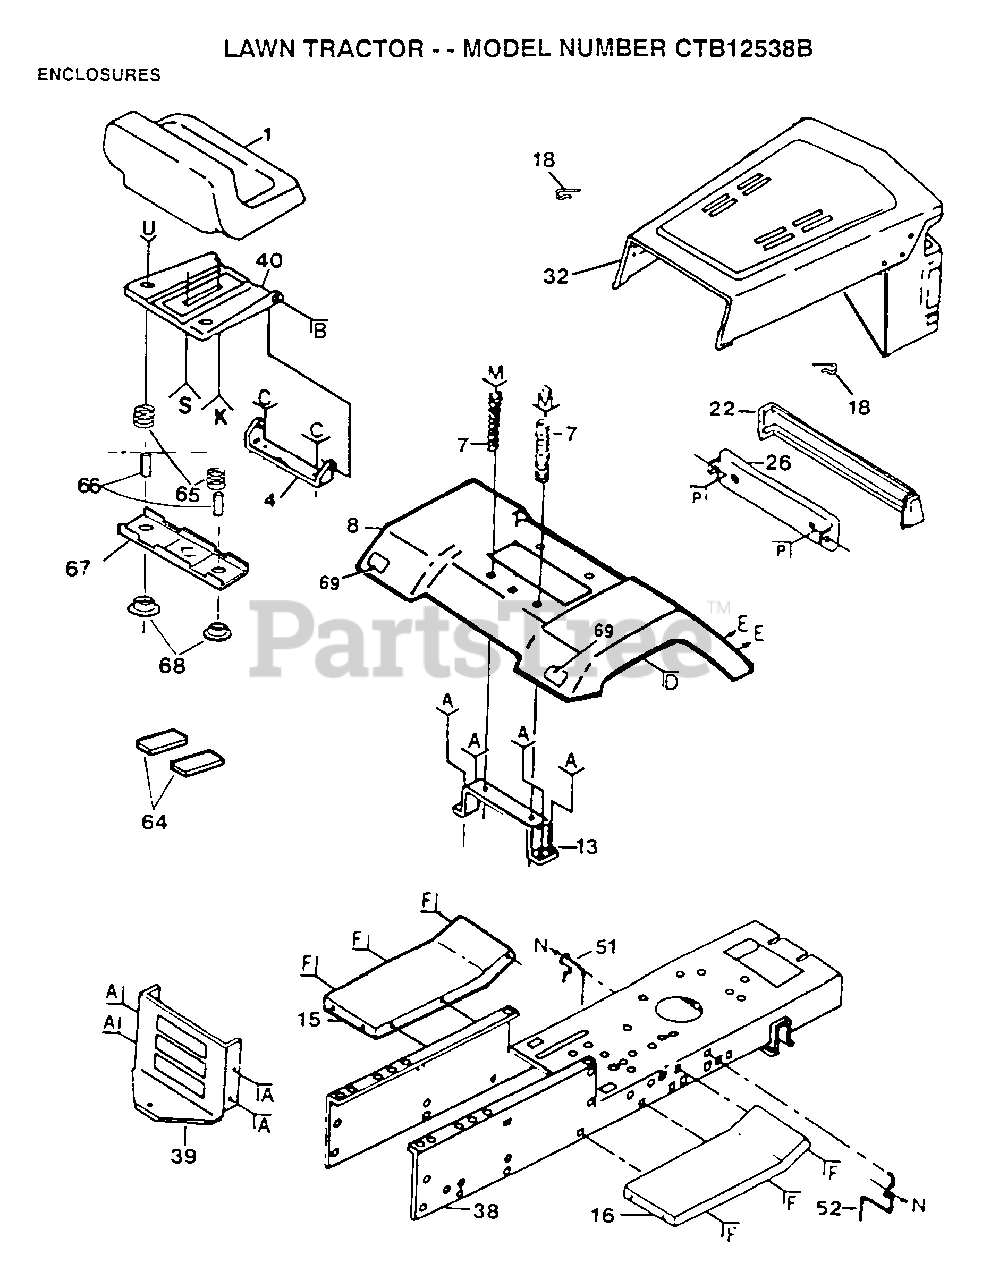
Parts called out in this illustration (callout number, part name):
7	SPRING COMPRESSIO
15	FOOTREST LH
16	FOOTREST
18	SPRING.RETAINER
32	HOOD&GRILL ASS'Y
38	CHASSIS ASS'Y
39	DRAWBAR LT/YT
51	BELT GUIDE
52	BELT GUIDE
64	STRIP FORM
65	SPRING COMPRESSED
66	SPACER SPLIT
67	BRKT SWITCH
68	BUSHING
69	REFLECTOR-TAIL YT
